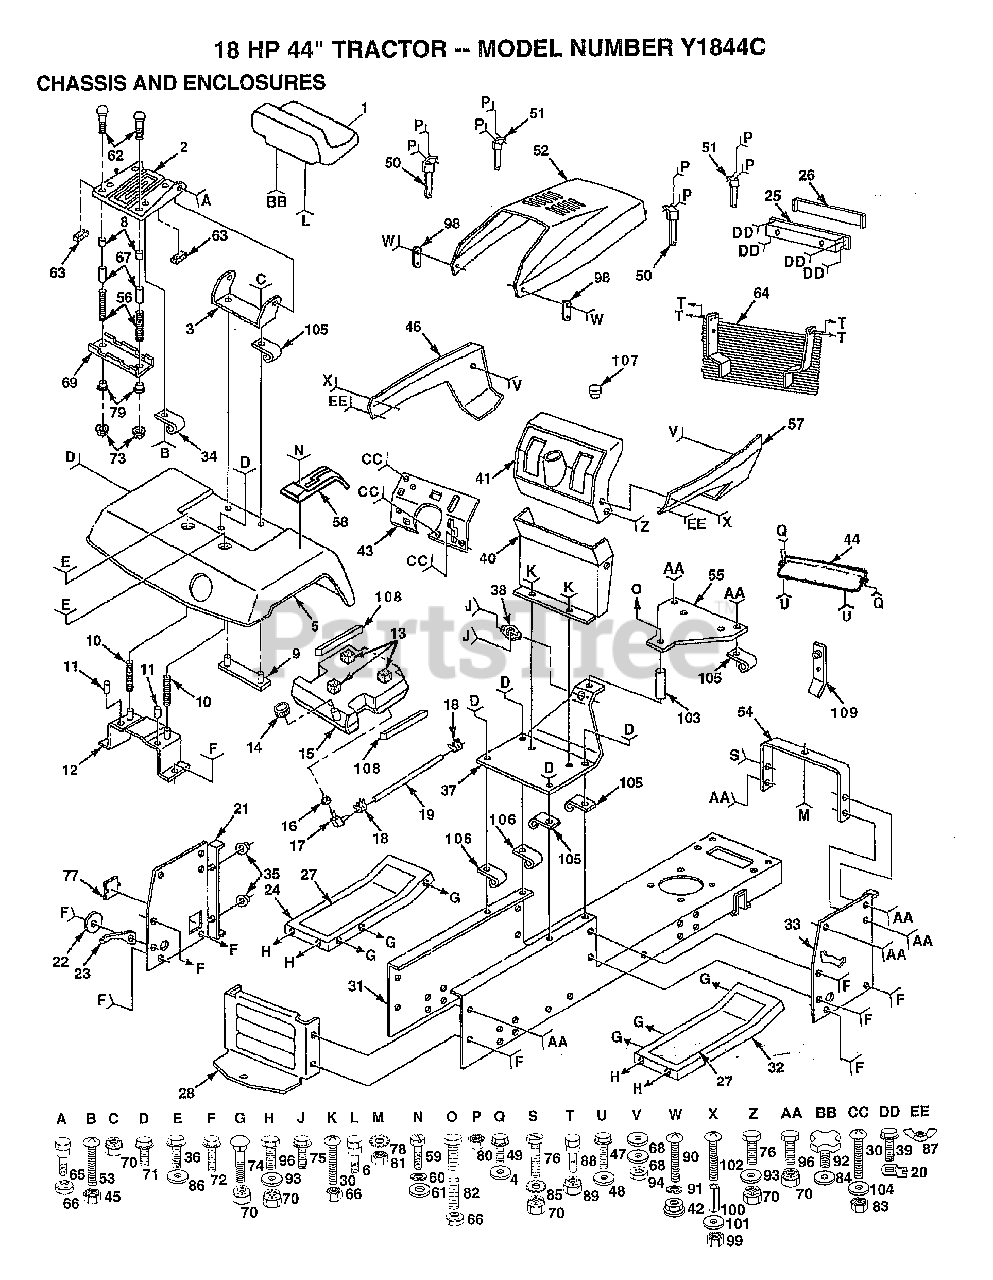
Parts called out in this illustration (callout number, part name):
4	WASHER
5	FENDER
6	"BOLT,SHOULDER"
8	CAP SPRING
10	SPRING COMPRESSIO
11	NUT-PUSH YT
12	BRKT.ASM.FENDER
13	PAD-SPACER LT
16	BUSHING OUTLET T
17	STEM.TANK.FUEL
18	HOSE CLAMP
20	"""J"" FASTENER LT"
21	PANEL.DASH.LH
22	WASHER T
23	POINTER HGT IND
26	LENS LT
27	FOOTREST PAD
28	DRAW BAR
30	SCREW
31	CHASSIS
33	PANEL.DASH.RH
36	SCREW LT
37	SADDLE.YT.GOOSE N
40	LOWER DASH
42	WELDNUT
43	PLATE.DASH.SLKSCR
45	"NUT,KEPS"
47	SCREW HEX CRT
48	WASHER
49	SCREW
54	SUPPORT ASS'Y
56	SPRING COMPRESSED
57	"PANEL,SIDE RH "
58	CONSOLE SHIFTER
59	SCREW
60	"WASHER,LOCK"
61	WASHER
63	STRIP FORM
67	SPACER SPLIT
68	WASHER PM
69	BRKT SWITCH
71	SCREW LT
72	SCREW
74	BOLT
76	BOLT
77	COVER ACCESS
79	BUSHING
80	NUT
82	BOLT
84	WASHER
85	LOCKWASHER
86	WASHER
90	SCREW
91	LOCKWASHER
92	"KNOB 1/2"" YT"
93	WASHER
98	HOOD LATCH T
100	SPACER LT
101	WASHER
102	SCREW
103	SPACER
104	WASHER
105	CLIP T
106	"CLIP,INSULATOR"
107	PLUG-DASH T
108	PAD IDLER TI
